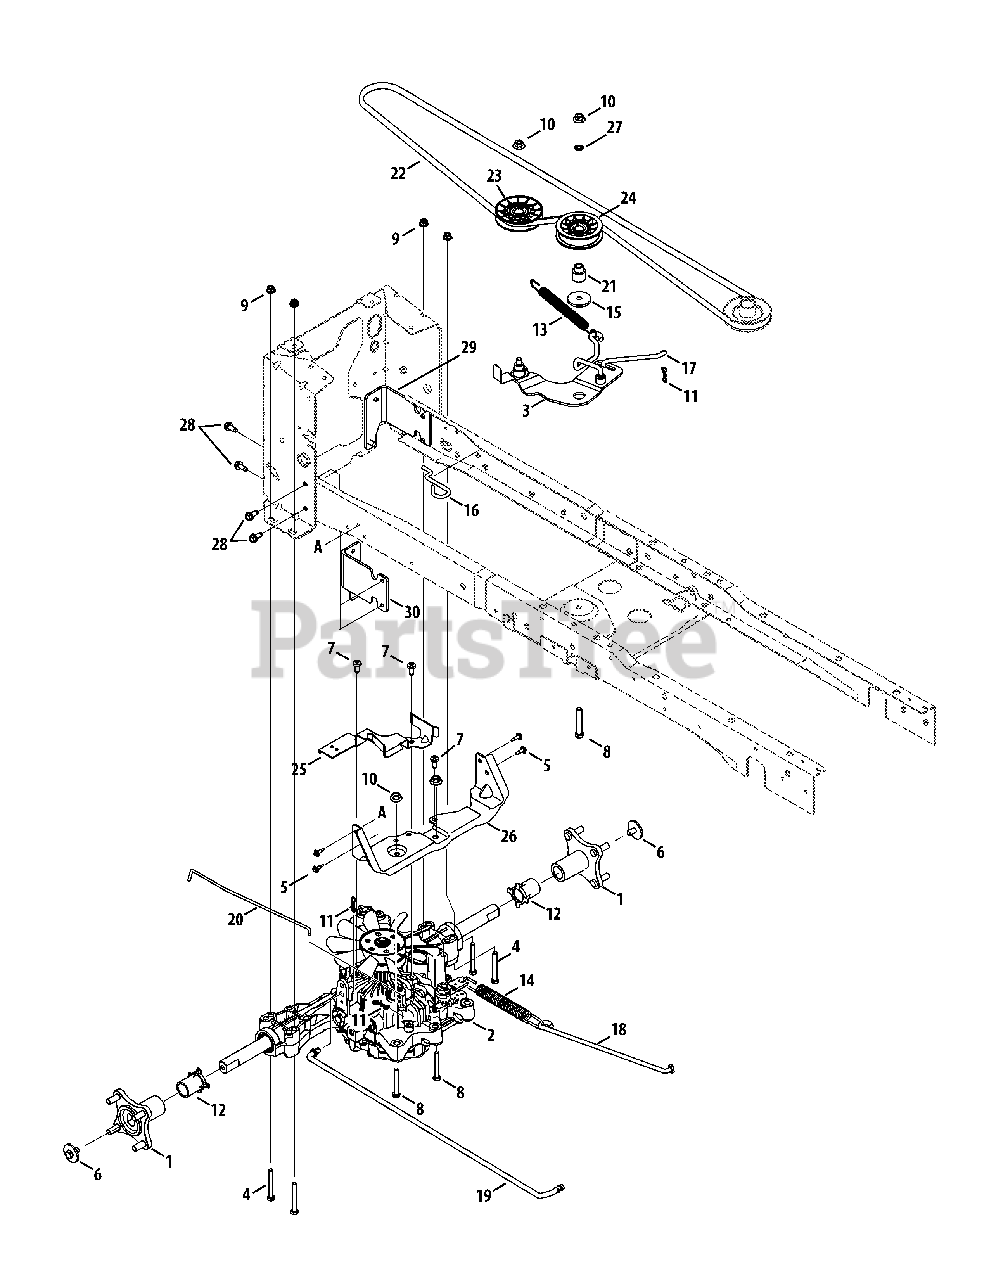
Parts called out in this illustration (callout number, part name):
1	Hub Assembly, Wheel
2	Transmission, Tuff Torq K58
3	Idler bracket Assembly
4	Hex Screw, 5/16-18, 2.75, Gr5, Std
5	Screw, M6-1 x .625
6	Hex Cap Screw, 3/8-16 x .750
7	Screw, Self-tapping, 5/16-18, 0.750
8	Hex Screw, 3/8-16, 2.25, Gr5
9	Nut, Flange Lock, 5/16-18, Nylon
10	Flange Lock Nut, 3/8-16
11	Pin, Cotter, Bow-Tie 72
12	Sleeve, 1.02 ID x 1.75
13	Spring, Extension, .700 Dia x 8.41
14	Spring, Extension, .90 Dia x 8.14
15	Shoulder Spacer, .884 x .190
16	Deck Spring Rod
17	Idler Link
18	Rod, Brake, Tuff Torq
19	Rod, Control, Tuff Torq
20	Rod, Transmission, Bypass
21	Shoulder Spacer
22	Belt, V-Type
23	Idler Pulley, 3.56 OD
24	Idler Pulley, 3.00 OD
25	Belt Keeper Bracket
26	Transmission Bracket
27	Speed Nut
28	Screw, Self-tapping, 5/16-18, 0.750,
29	Frame Support Bracket, LH
30	Frame Support Bracket, RH
